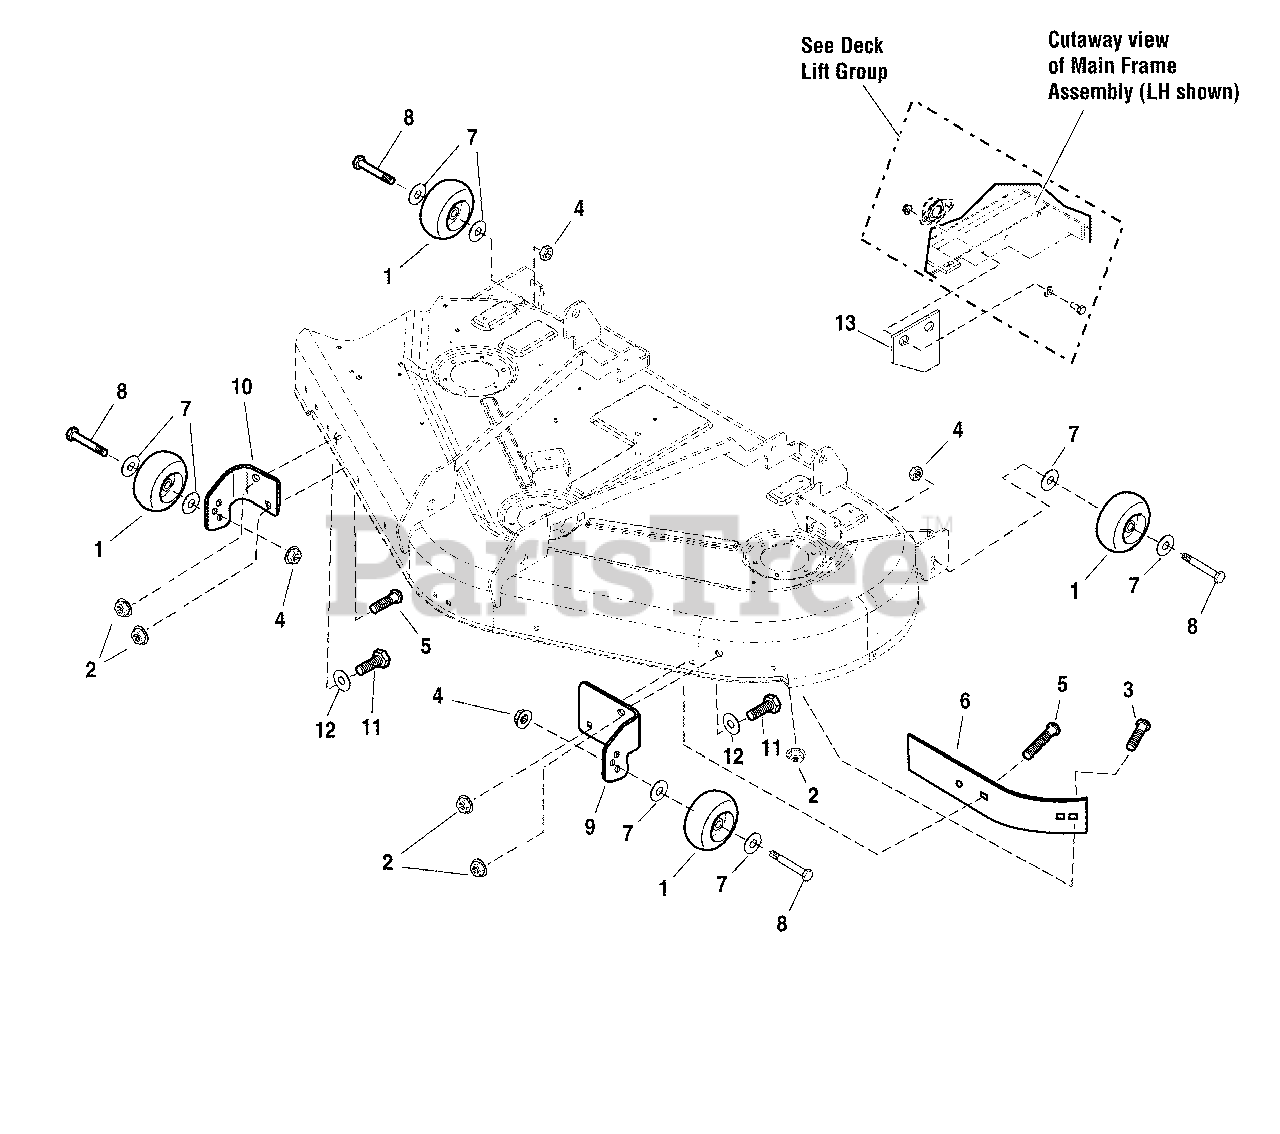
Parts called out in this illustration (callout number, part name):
1	WHEEL, 2.00 WIDE 3.92 DIA 0.531 ID POLY
2	NUT, 5/16-18 HEX NYLOCK FLANGE
3	BOLT, 5/16-18 X 3/4", CARRIAGE
4	NUT, 3/8-16 HEX NYLOCK FLANGE
5	BOLT, 5/16-18 X 1, CARRIAGE
6	SHORT BLOWOUT BAFFLE BLACK
7	WASHER, 0500 (0.51 ID X 0.87 OD X .06 THK) BLK
8	BOLT, WHEEL 3/8-16 X 2.781 .750 THRD YELLOW
9	BRACKET, GUAGE WHEEL, LH
10	BRACKET, GAUGE WHEEL, RH
11	BOLT, 5/16-18 X 1 GD5 YZ
12	WASHER, 5/16" SAE
13	BAFFLE FRONT 50" MOWER
